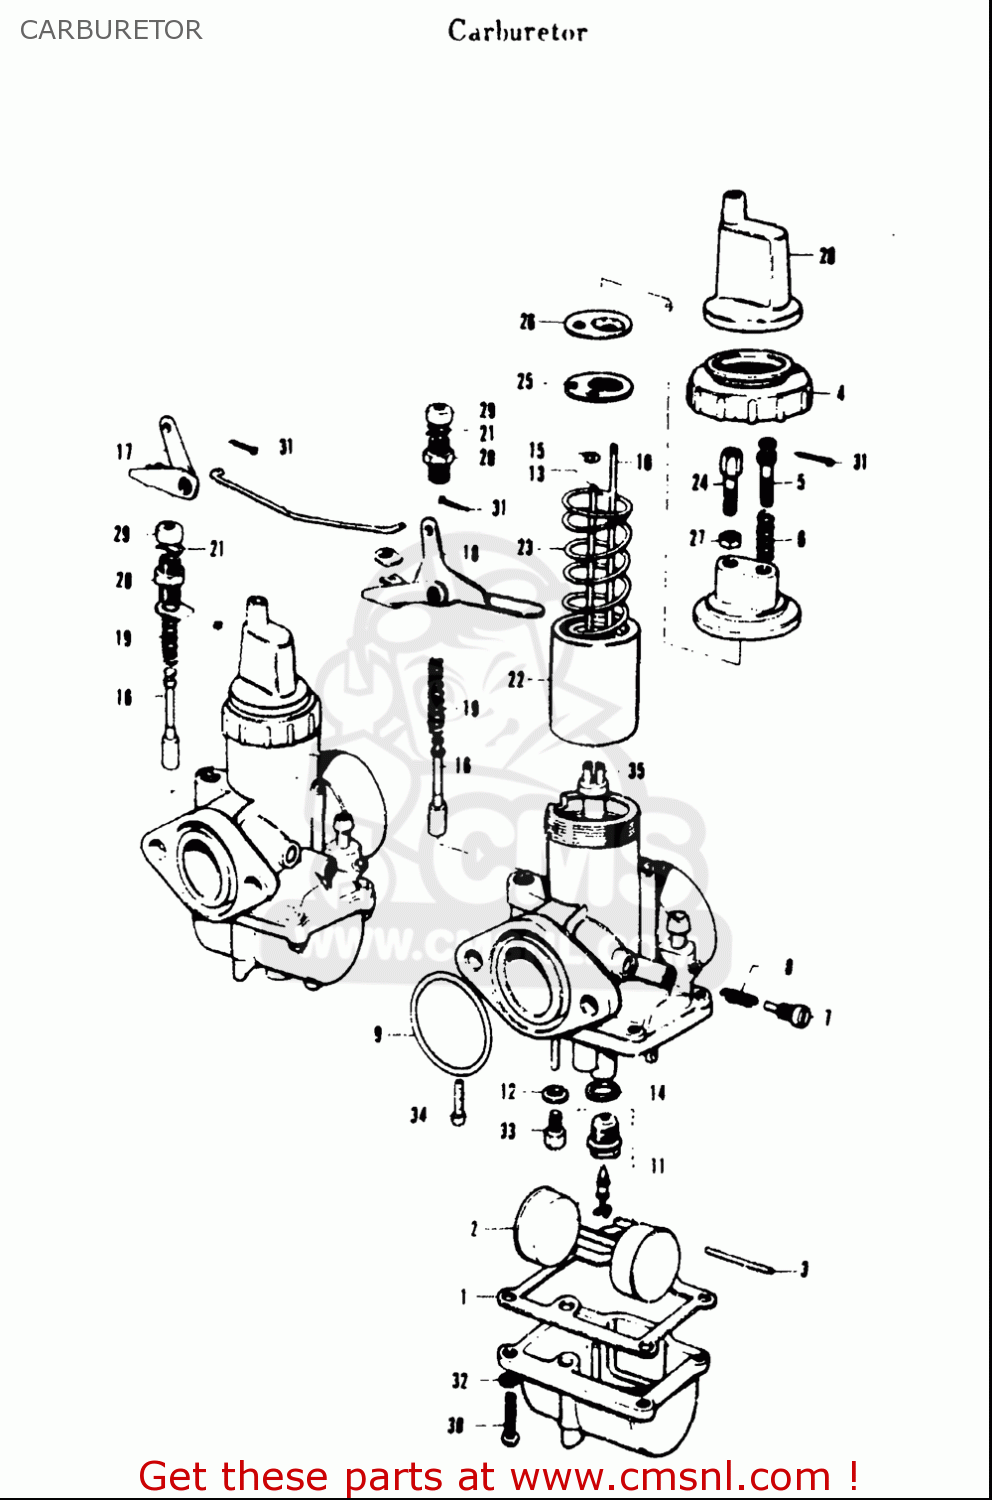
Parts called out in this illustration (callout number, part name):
1	GASKET,FLOAT CHAMBER (NAS)
2	FLOAT
5	SCREW,THROTTLE VALVE ADJUST
6	SPRING,THROTTLE SCREW
7	SCREW,PILOT AIR ADJUSTING
10	ROD,THROTTLE VALVE ADJUST
11	VALVE ASSY,NEEDLE
12	WASHER
14	GASKET,NEEDLE VALVE (NAS)
15	CLIP,NEEDLE
24	ADJUSTER,CABLE
27	NUT
29	CAP,PLUNGER
32	WASHER,LOCK
33	JET,MAIN
34	JET,PILOT
